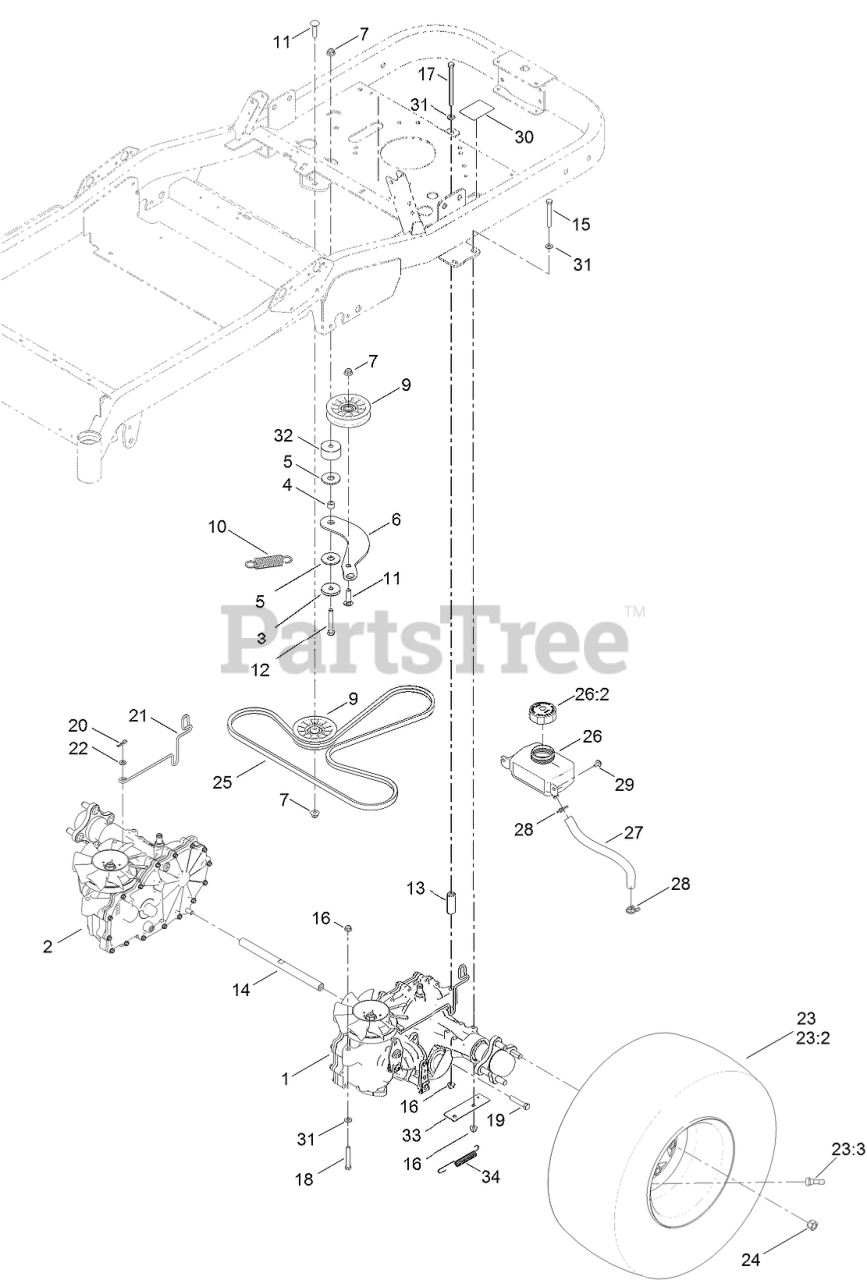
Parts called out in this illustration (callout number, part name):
1	LH HYDRO TRANSMISSION ASM
2	RH HYDRO TRANSMISSION ASM
3	WASHER-PLAIN
4	SPACER
5	WASHER-FRICTION, COMPOSITE
6	ARM-IDLER
7	NUT-HF, NI
9	PULLEY-IDLER, FLAT
10	SPRING-EXTENSION
11	SCREW-CARR
12	SCREW-HH
13	SPACER-HYDRO
14	SHAFT-CROSS, HYDRO
15	SCREW-HH
16	NUT-HF, NI
17	SCREW-HH
18	SCREW-HH
19	SCREW-HH
20	PIN-COTTER
21	ROD-BYPASS
22	WASHER-FLAT
23	TIRE AND WHEEL ASM
23:3	STEM-VALVE
24	NUT-LUG
25	V-BELT
26	HYD RESERVIOR ASM
26:2	CAP-RESERVOIR, HYD
27	HOSE-OVERFLOW
28	CLAMP-HOSE
29	SCREW-HHFTF
30	DECAL-BYPASS
31	WASHER-PLAIN
32	SPACER
33	PLATE-SPRING
34	SPRING-EXTENSION
